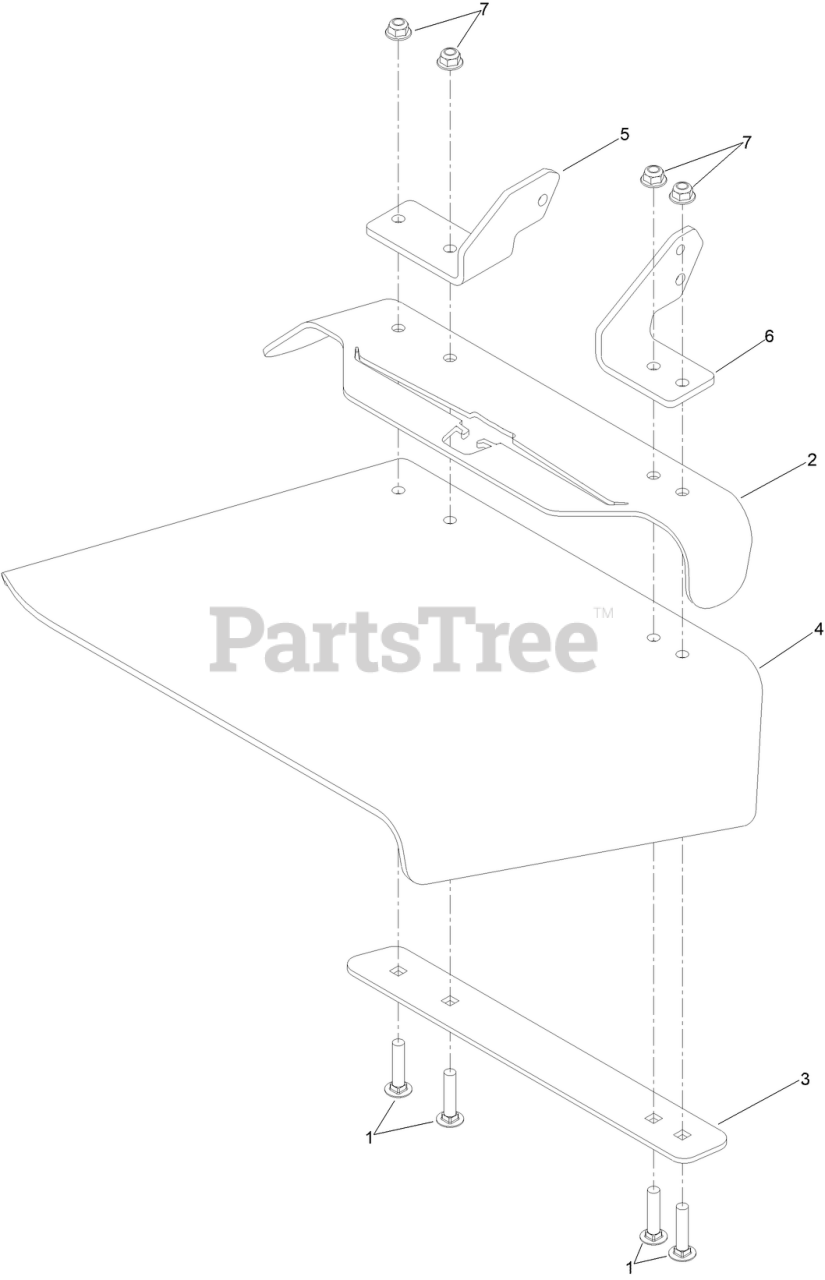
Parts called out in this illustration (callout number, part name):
1	SCREW-CARR
2	PLATE-DEFLECTOR MOUNT
3	STRAP-DISCHARGE
4	DEFLECTOR-DECK, RUBBER
5	PLATE-HINGE, REAR
6	PLATE-HINGE, FRONT
7	NUT-HF, NI
